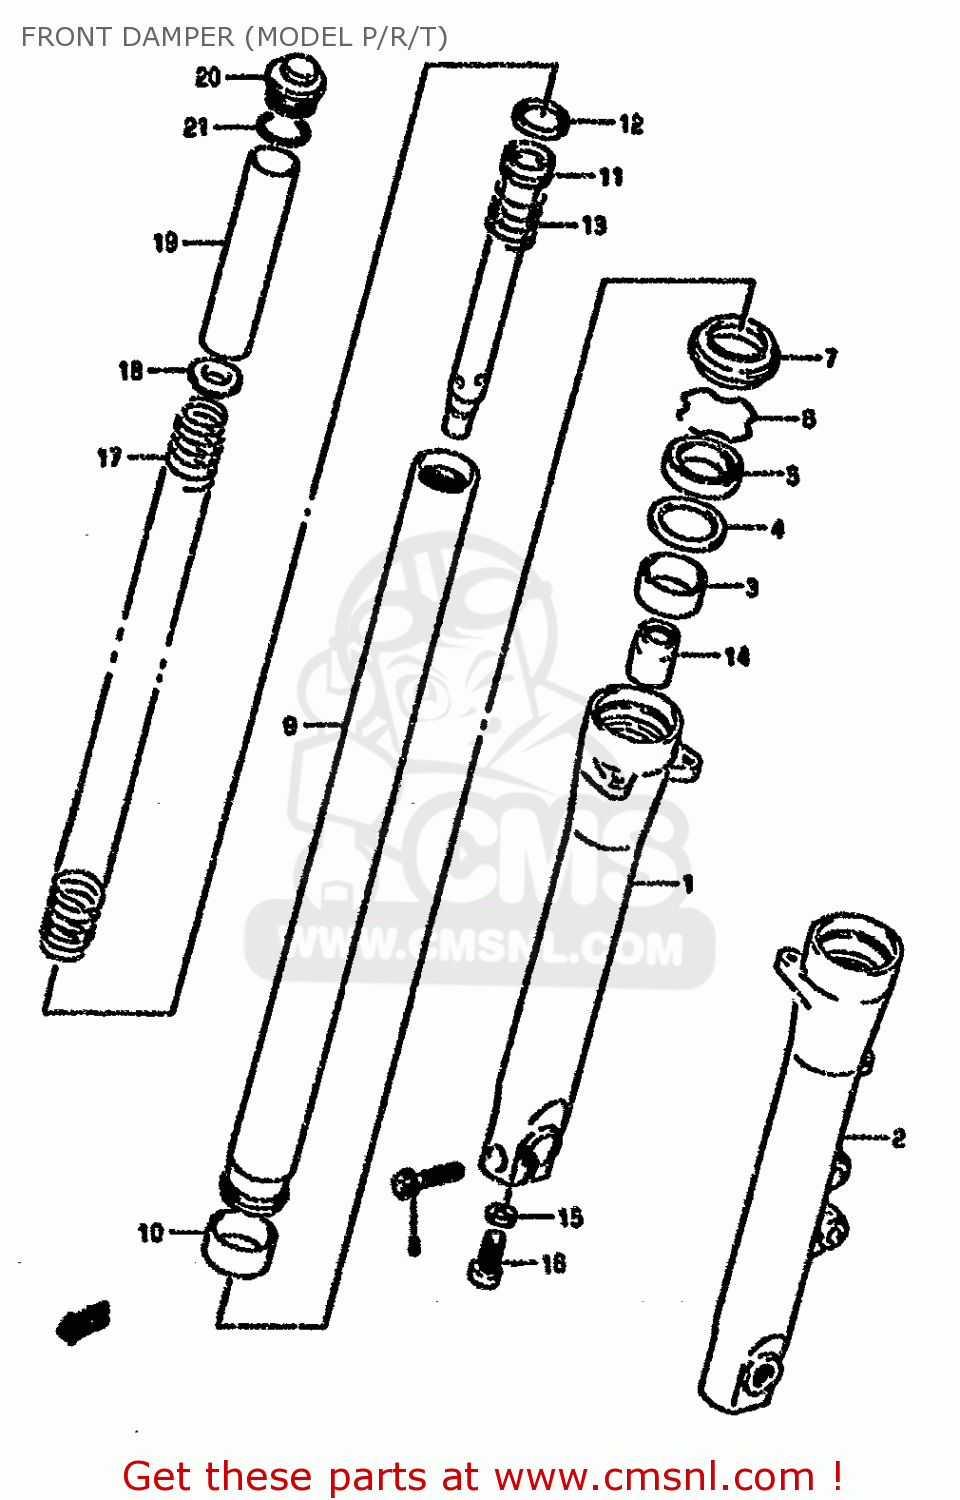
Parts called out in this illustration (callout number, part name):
1	TUBE,OUTER,RIGHT
2	TUBE,OUTER,L
3	METAL,SLIDE
4	WASHER,FORK OIL SEAL
5	OIL SEAL,FRONT FORK
6	RING,OIL SEAL STOPPER
7	SEAL,DUST
8	BOLT
9	TUBE,INNER
10	PISTON
11	CYLINDER
12	RING,PISTON
13	SPRING,REBOUND
14	PIECE,OIL LOCK
15	GASKET (NAS)
16	BOLT,FORK CYLINDER(10X25)
17	SPRING,MAIN
18	WASHER
19	SPACER,SPRING
20	CAP,FORK
21	O RING
